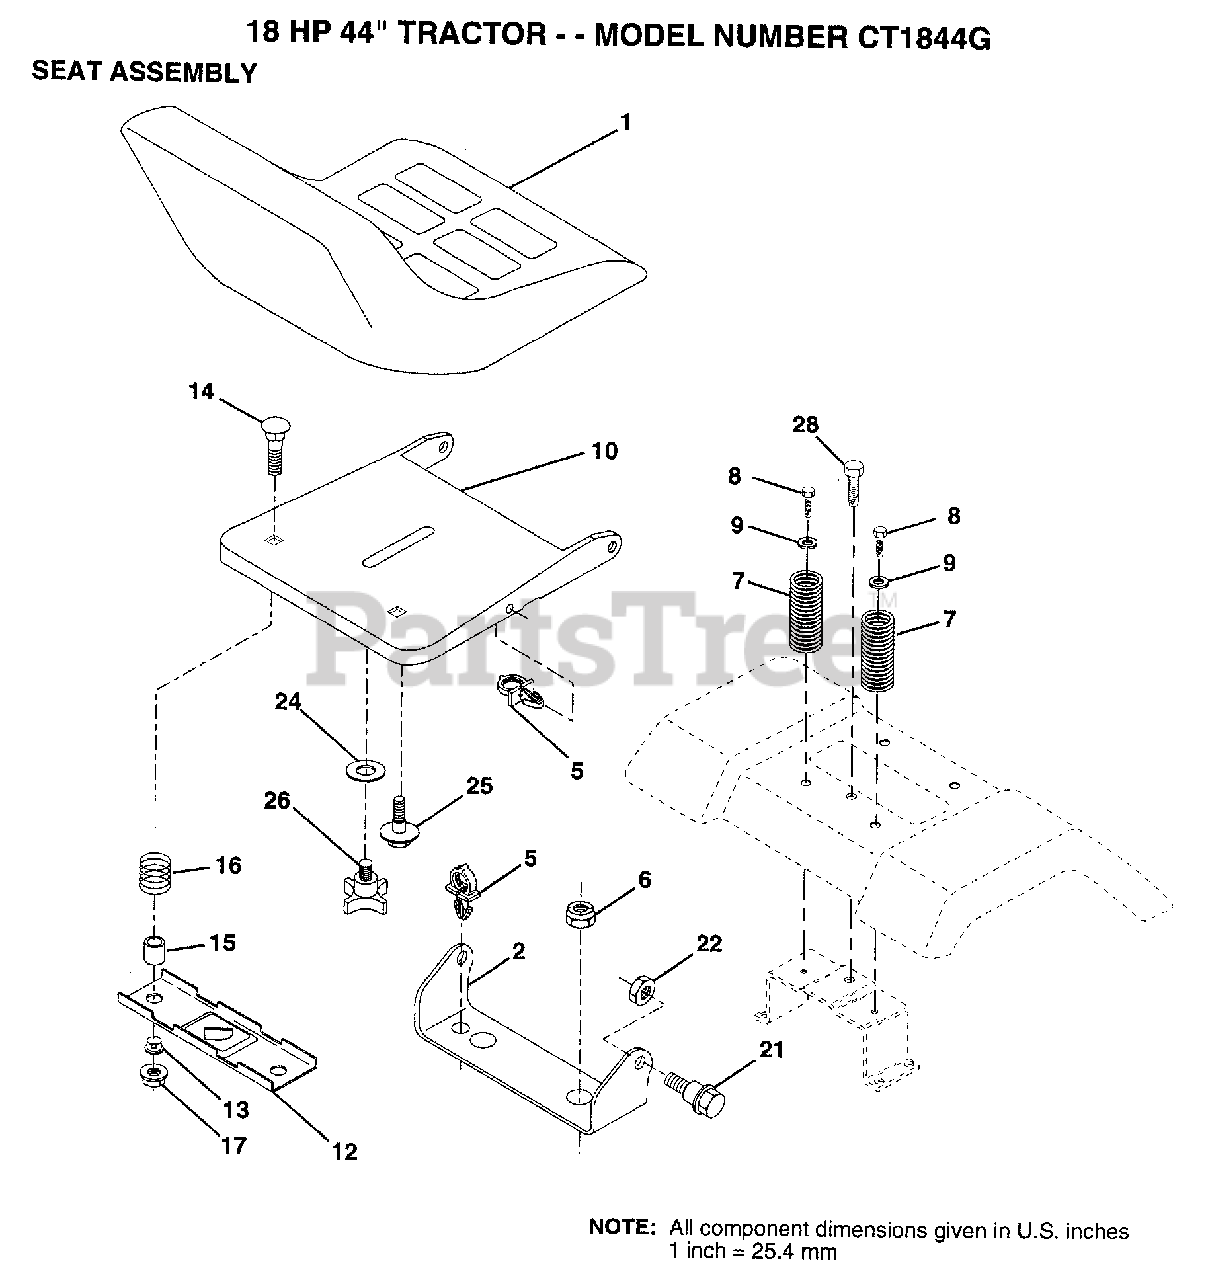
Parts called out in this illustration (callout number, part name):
2	BRACKET PVT SEAT
5	CLIP PUSH - IN
7	SPRING COMPRESSIO
8	SCREW LT
9	WASHER
12	BRKT SWITCH
13	BUSHING
15	SPACER SPLIT
16	SPRING COMPRESSED
21	BOLT.SHLD.5/16-18
24	WASHER
25	"BOLT,SHOULDER"
26	"KNOB 1/2"" YT"
28	SCREW LT
